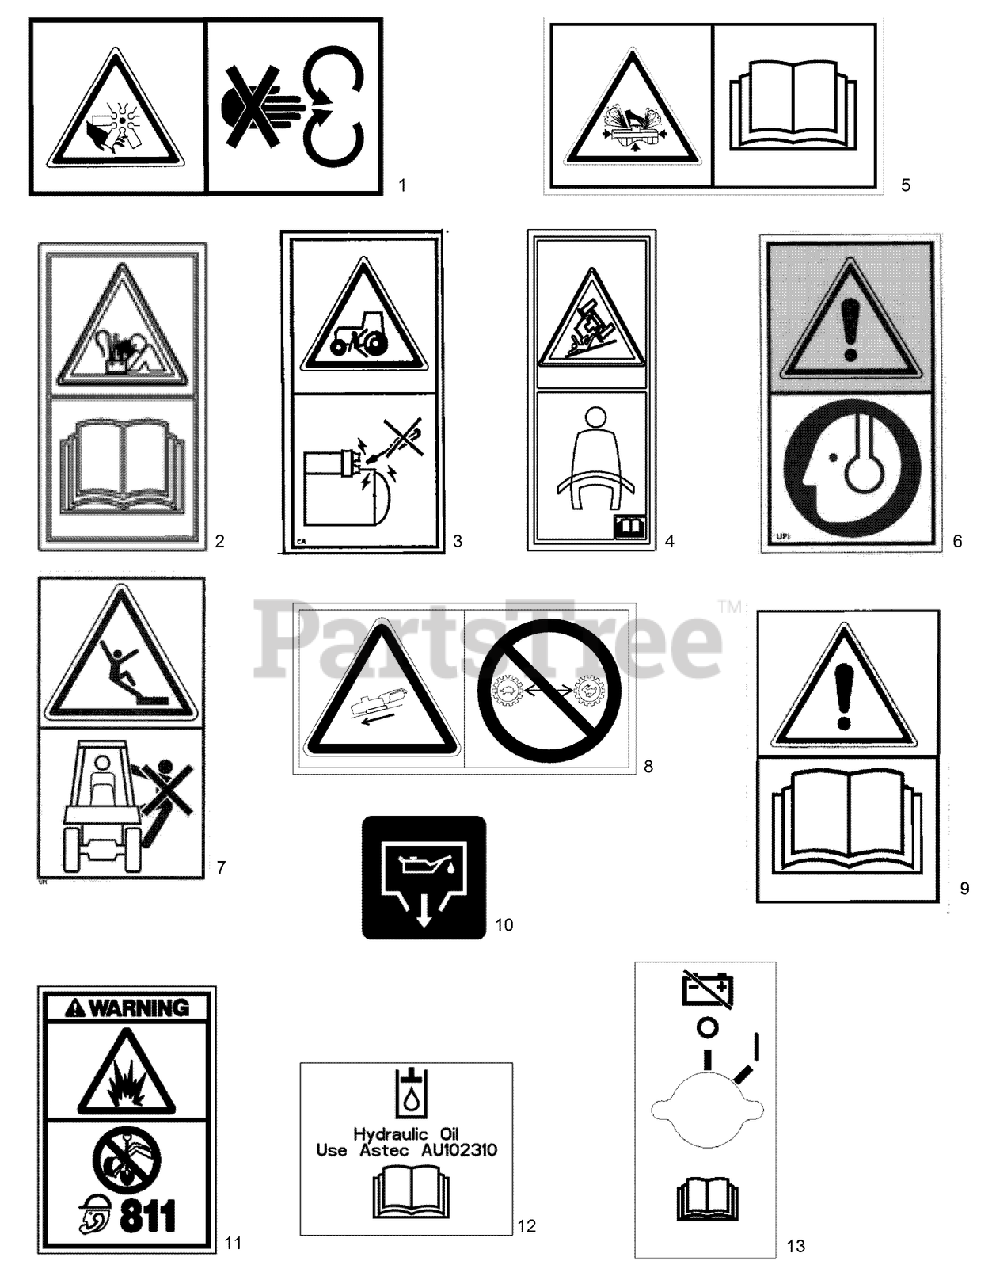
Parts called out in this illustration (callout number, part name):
1	DECAL-Fan Entanglement
2	DECAL-Battery Explosion
3	DECAL - Runover Hazard
4	DECAL-Warning, Fasten Seat Belt
5	DECAL-Fluid Pressure
6	DECAL-Warning, Hearing Protection Required
7	DECAL-No Riders
8	DECAL-Unexpected Movement
9	DECAL-Read Operators Manual
10	DECAL - Engine Oil Drain
11	DECAL-Warning, Call Before Digging
12	DECAL - Hydraulic Fluid.
13	DECAL-Master Disconnect Switch
